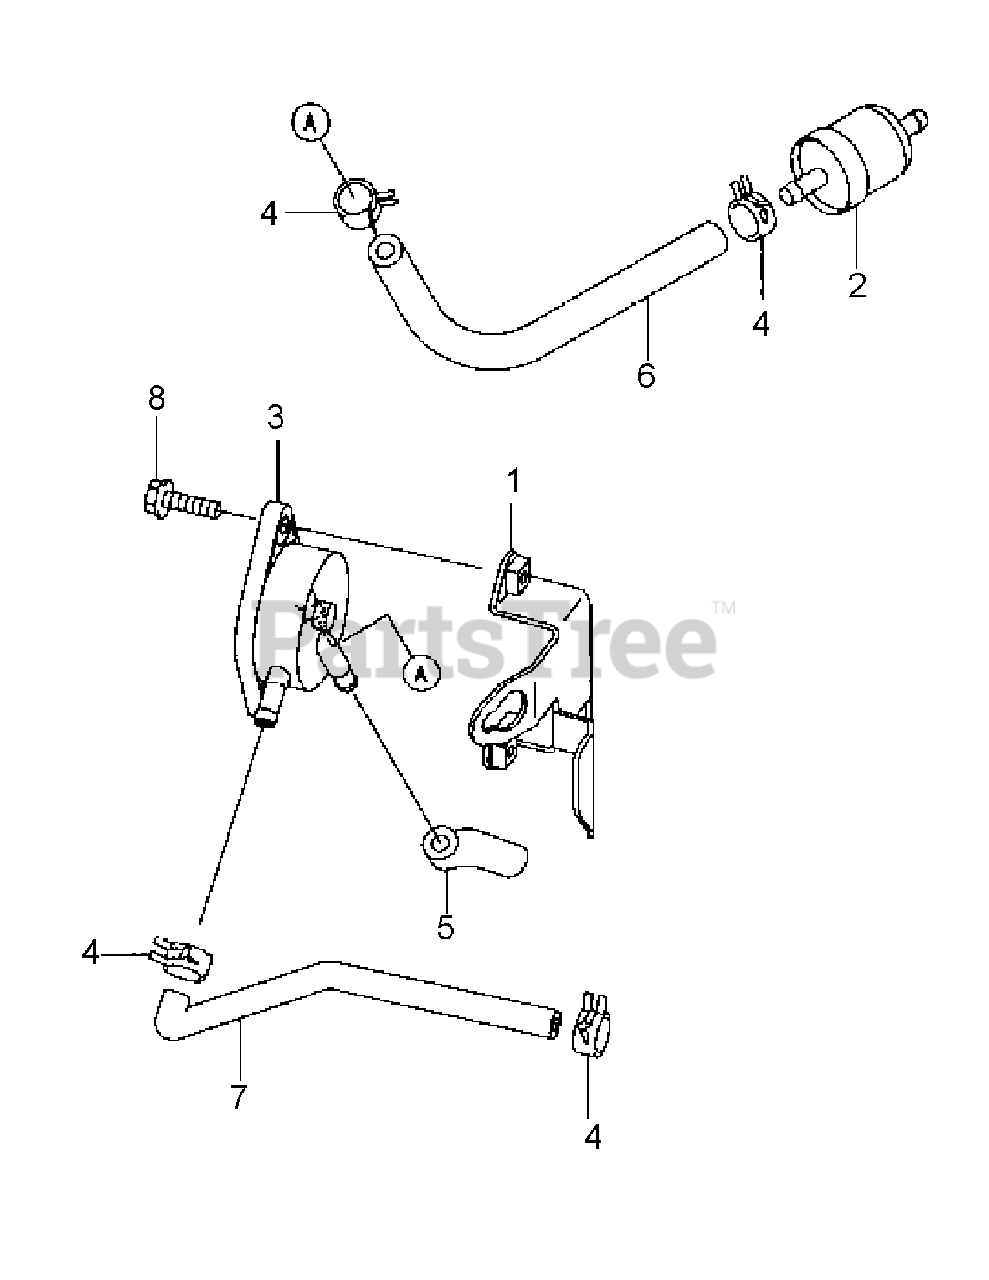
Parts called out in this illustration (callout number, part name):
2	FUEL FILTER
3	FUEL PUMP
4	CLAMP
6	TUBE, 6.35x12.7x160
8	FLANGED BOLT
